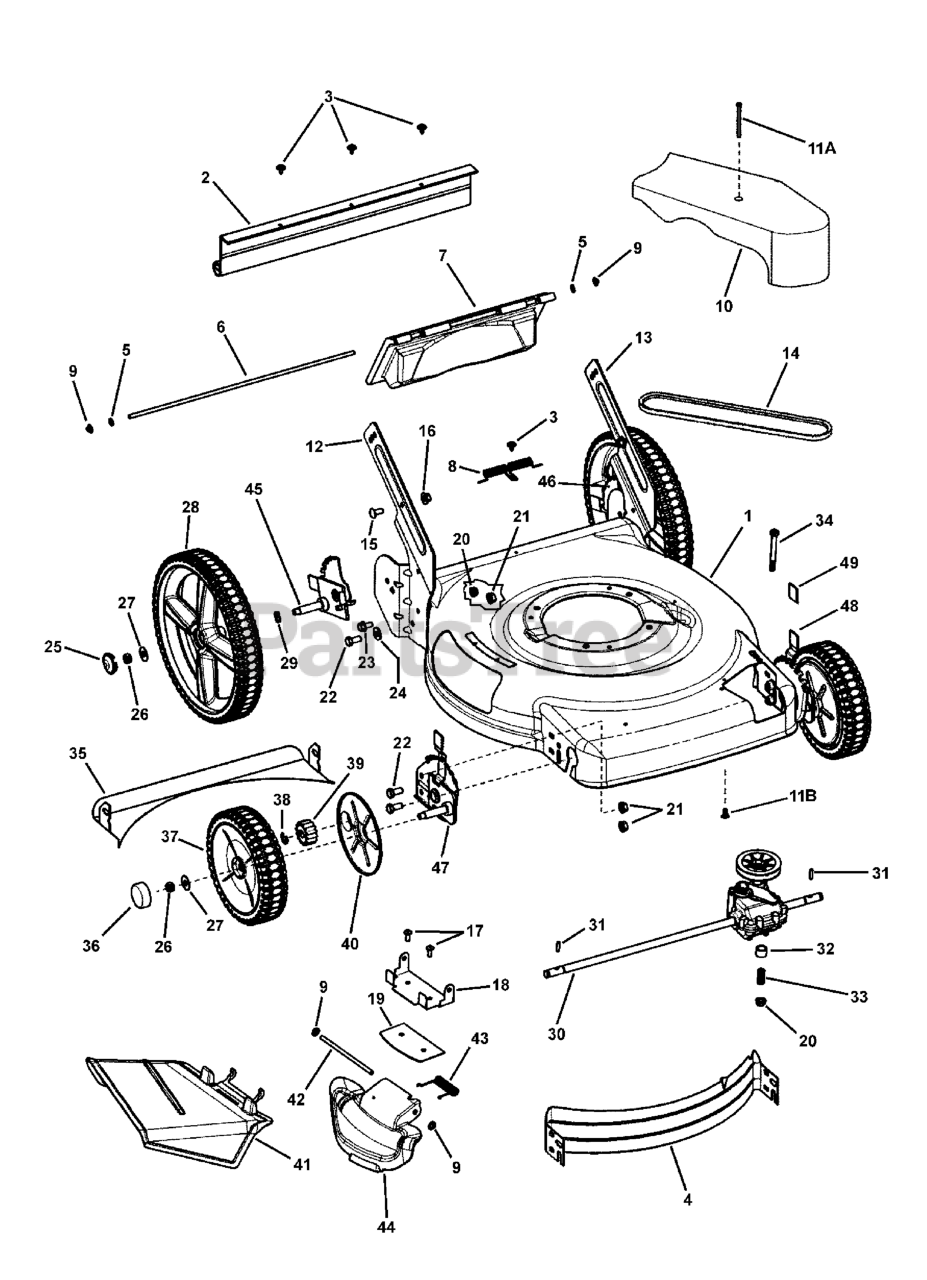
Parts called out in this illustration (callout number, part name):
1	DECK, 22" Walk, 3-N-1
2	GUARD, Rear 22" HW (19-1/2" long)
2	GUARD, Rear
3	SCREW, Self Tap, Sems, 10-24 x 1/2
4	BAFFLE, Front
5	CAP, Retainer
6	ROD, Pivot, Rear Door
7	DOOR, Rear Discharge
8	SPRING, Torsion
9	PUSHNUT, 1/4
10	COVER, Belt
11A	SCREW, #10-24 X 2-1/2
11B	SCREW, Round Washer Head Torx, Hi-Lo
14	BELT, Drive, (3L Section; 33.75" effective length)
15	BOLT, Carriage, 5/16-18 x 3/4 GR5
16	NUT, Hex Flange, Centerlock, 5/16-18
17	SCREW, Torx, 1/4-20 x 11/16
18	BRACKET, Chute
19	PLATE, Mulch
20	NUT, Hex Flange Lock, 5/16-18
21	NUT, Hex Flange, 3/8-16
22	CAPSCREW, Hex Head, 3/8-16 x 3/4
23	BOLT, Hex Flange, 5/16-18 x 5/8
24	WASHER, Flat, 3/8 ID, 7/8 OD
25	HUBCAP, 12" Wheel
26	NUT, Center Lock, 3/8-16
27	WASHER, Flat, 3/8 ID, 1" OD
28	WHEEL, 12"X 2" Idle
29	WASHER, Wave
30	TRANSMISSION
31	PIN, Drive
32	SPACER, Engine
33	SPRING, Compression
34	BOLT, Hex-Head 5/16-18 x 3
35	BAFFLE, Rear
36	HUBCAP, Round
37	WHEEL, 8"X 2" Drive
38	RING, Retaining
39	GEAR, Pinion
40	SHIELD, Dust
41	CHUTE, Side
42	ROD, Pivot, Chute
43	SPRING, Torsion, Chute
44	COVER, Mulch
45	ASSY, Height-Of-Cut, RR, 22", 7 Position (shown detached)
45	ASSY, Height-Of-Cut, RR, 22", 9 Position (shown detached)
46	ASSY, Height-Of-Cut, RR, 22", 7 Position (shown attached)
46	ASSY, Height-Of-Cut, LR, 22", 9 Position (shown attached)
47	ASSY, Height-Of-Cut, RF, 22", Propelled, 7 Position (shown detached)
47	ASSY, Height-Of-Cut, RF, 22", Propelled, 9 Position (shown detached)
48	ASSY, Height-Of-Cut, LF, 22", Propelled, 7 Position (shown attached)
48	ASSY, Height-Of-Cut, LF, 22", Propelled, 9 Position (shown attached)
49	GRIP, Height Latch
